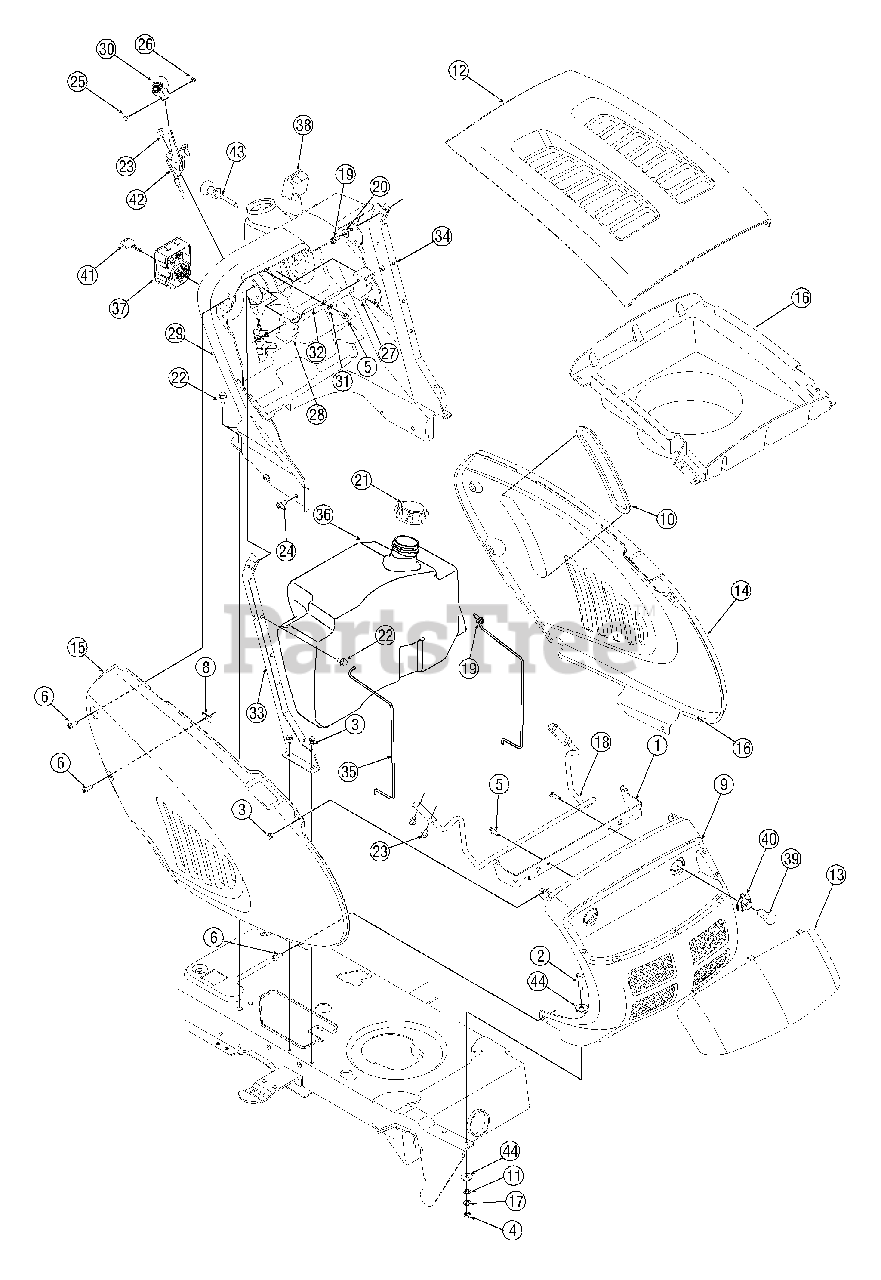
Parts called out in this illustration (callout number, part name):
2	Screw, 5/16-18 x 1.25
3	Screw, 1/4-20, 0.500
4	Hex Nut, 5/16-18
5	Screw, 1/4-15, 0.750
6	Screw, Machine, 1/4-20, 0.750
7	Cable Tie
8	Nut, Clip, 1/4-20
9	Grill, 9 Style
9	Grill, 9 Style, Service Kit
10	Panel Seal
11	Nut, Speed,.3125 ID
16	Plenum, Super Bronco (Model T609)
17	Washer, Lock, 5/16
18	Hinge Rod
19	Screw, 1/4-20 x.75
20	Washer, Bell,.265 x.75 x.062
21	Fuel Cap
22	Screw, 5/16-12, 0.750
23	Screw, 1/4-14, 0.625
24	Screw, 5/16-18, 0.750
25	Screw, Machine, #8-32, 0.375
26	Nut, Hex, #8-32
27	Brake Lever
28	Cruise Control Lever
29	Dash Panel
30	Control Knob
31	Washer, Flat,.281 x.50 x.063
32	Rod, Brake / Cruise Pivot
35	Fuel Tank Support - RH
35	Fuel Tank Support - LH
36	Fuel Tank, 3 Gal.
37	Ignition Switch Module
38	Ammeter
39	Miniature Lamp, 12V
40	Socket, Lamp
41	Key, Ignition
41	Key w/ Plastic Cover, Ignition
42	Throttle Cable, 39", Super Bronco
42	Throttle/Choke Cable, Bronco
43	Choke Knob w/ Cable, 37.5" Super Bronco
44	Washer, Flat,.344 x 1.0 x.063
